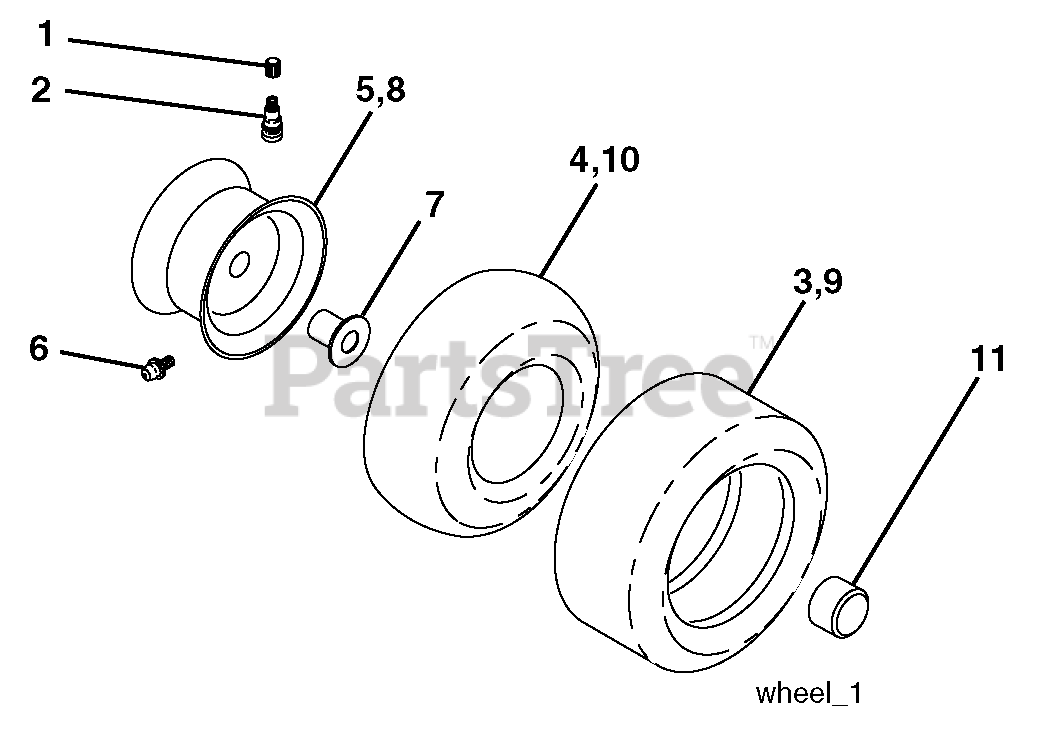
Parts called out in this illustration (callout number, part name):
1	Cap Value Tire
3	Tire F Ts 15 x 6 0 - 6 Service
4	Tube Inner Front #35060
5	Rim Asm 6" front Service
6	Fitting Grease
7	Bearing Flange
8	Rim Asm 8" rear Service
9	Tire R Ts 20 x 8-8 C. Service
10	Tube Rear 9 5 x 8 Service
11	Cap Axle Blk 1 50 x 1 00
11	Sealant, Tire (10 oz. tube)
